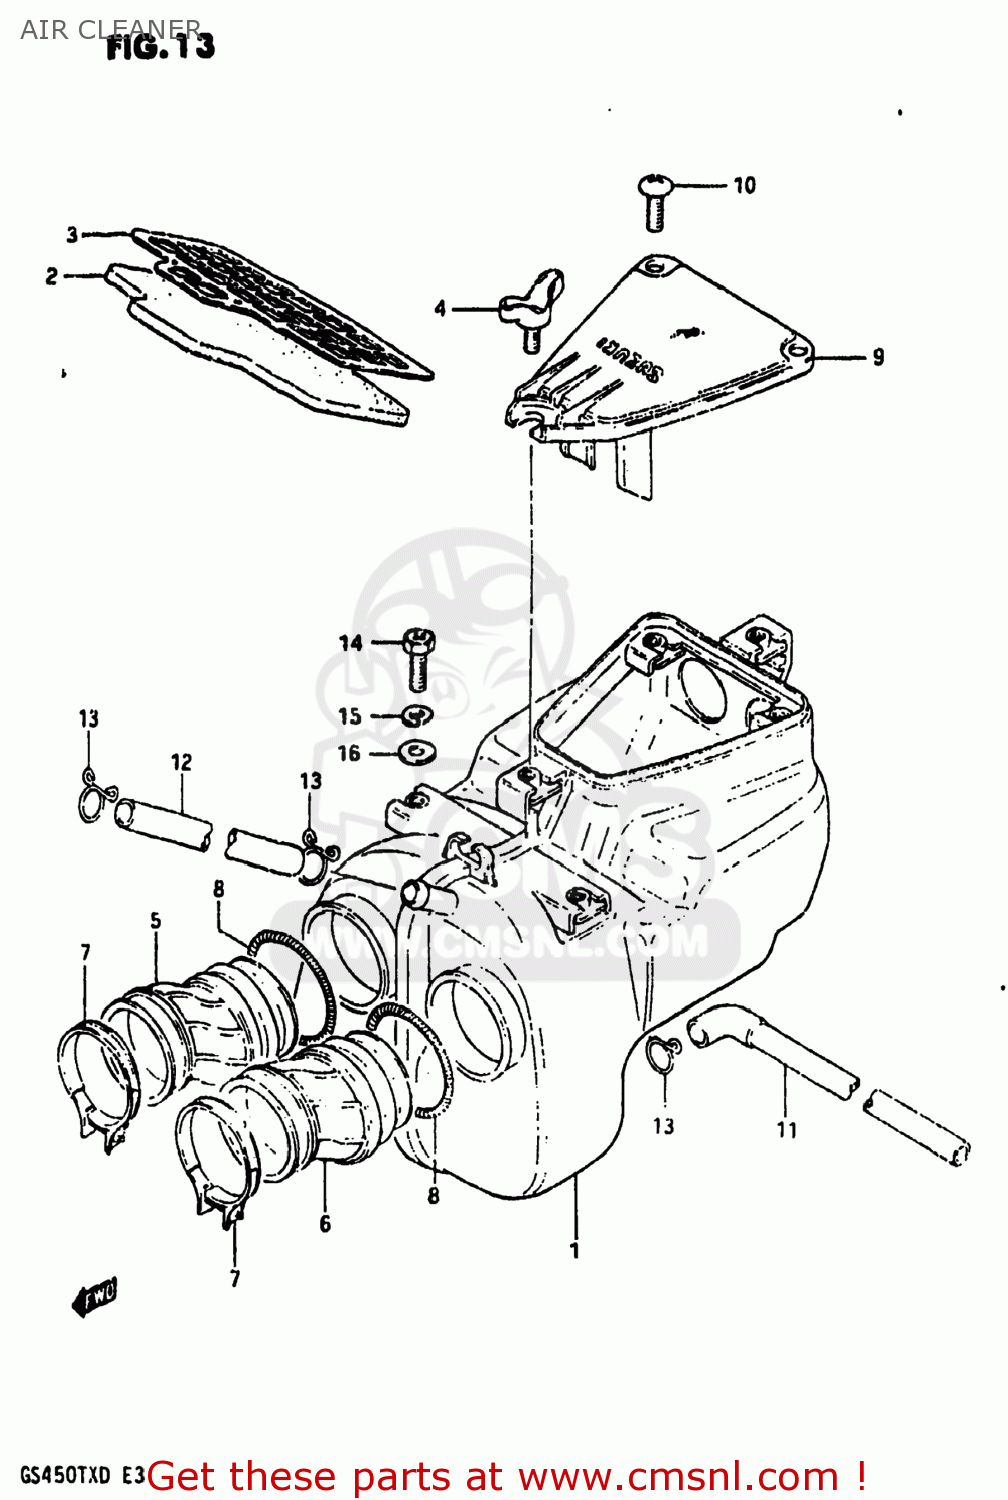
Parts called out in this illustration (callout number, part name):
1	CLEANER ASSEMBLY,AIR
2	FILTER
3	HOLDER,OUTER
4	BOLT, WING
5	TUBE,OUTLET,R
6	TUBE,OUTLET,L
7	CLAMP
8	CLAMP,CLEANER SIDE
9	CAP,AIR CLEANER
10	SCREW
11	DRAIN TUBE
12	TUBE,BREATHER
13	CLAMP
14	SCREW(6X12)
15	LOCK WASHER
16	WASHER
